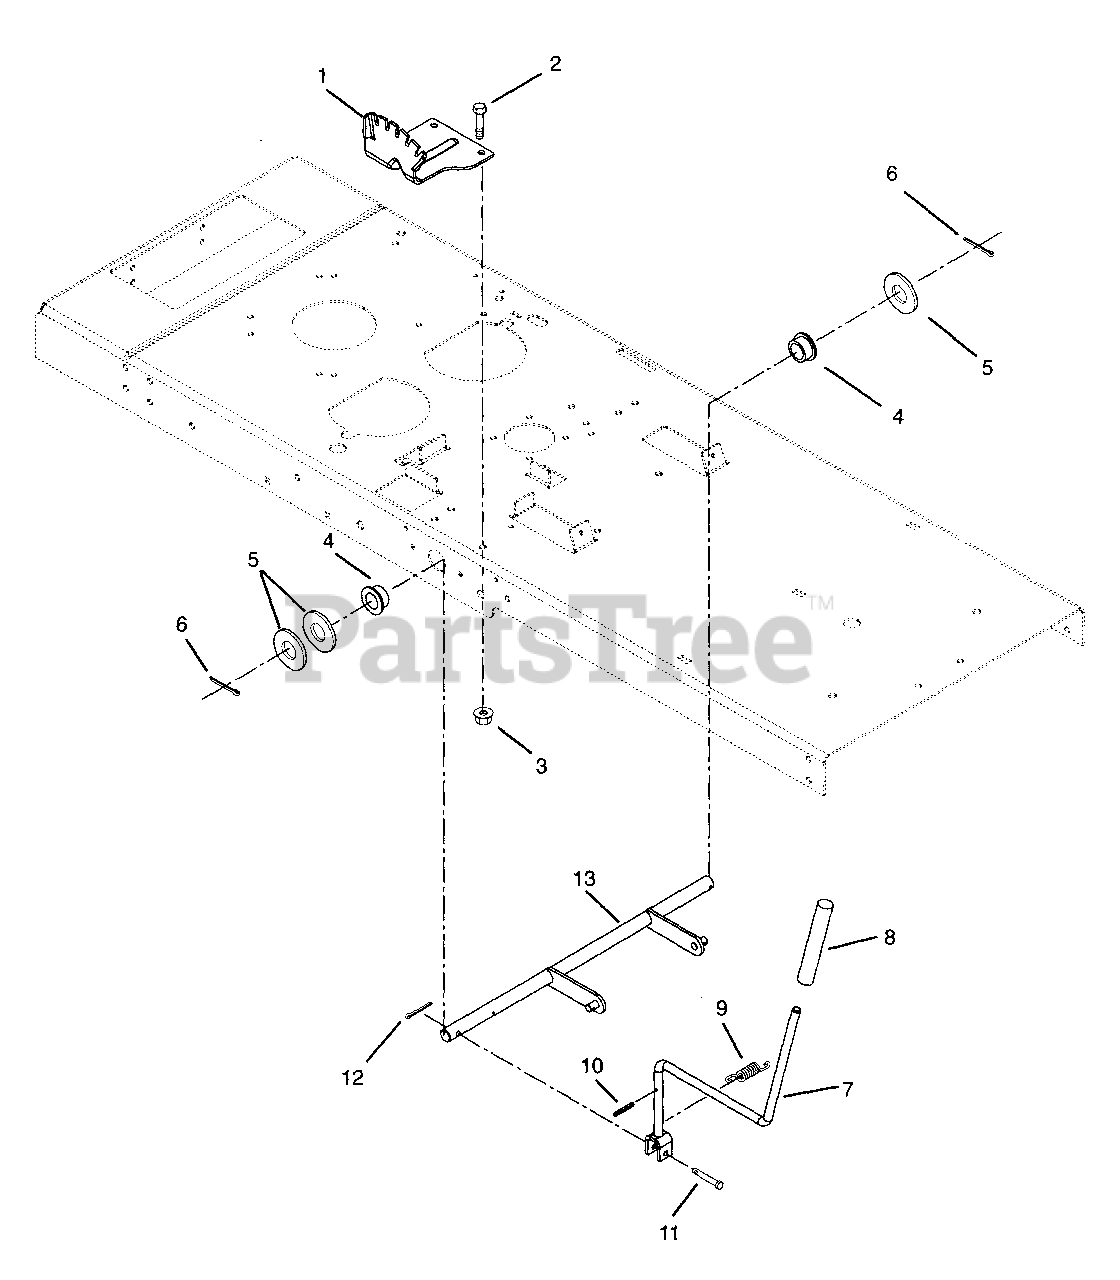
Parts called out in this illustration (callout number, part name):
1	DETENT PLATE
2	BLT-HEX .38-16X1.00 PL GR5
3	NUT-LK-CTR .375-16 GR A PL
4	BSHG-FLG1.020X1.385X.75X1.75NY
5	WSHR-FL-STL 1.062X2.000X.134
6	PIN-COTR .188X1.50
7	LIFT LEVER WELDMENT
9	SG-TENS .120X1.0X4.46 WLD 47
10	PIN-ROLL .250X1.00
11	PIN-CLEV .370X1.75
12	PIN-COTR .12X1.0 PL
13	LIFT SHAFT WELDMENT
